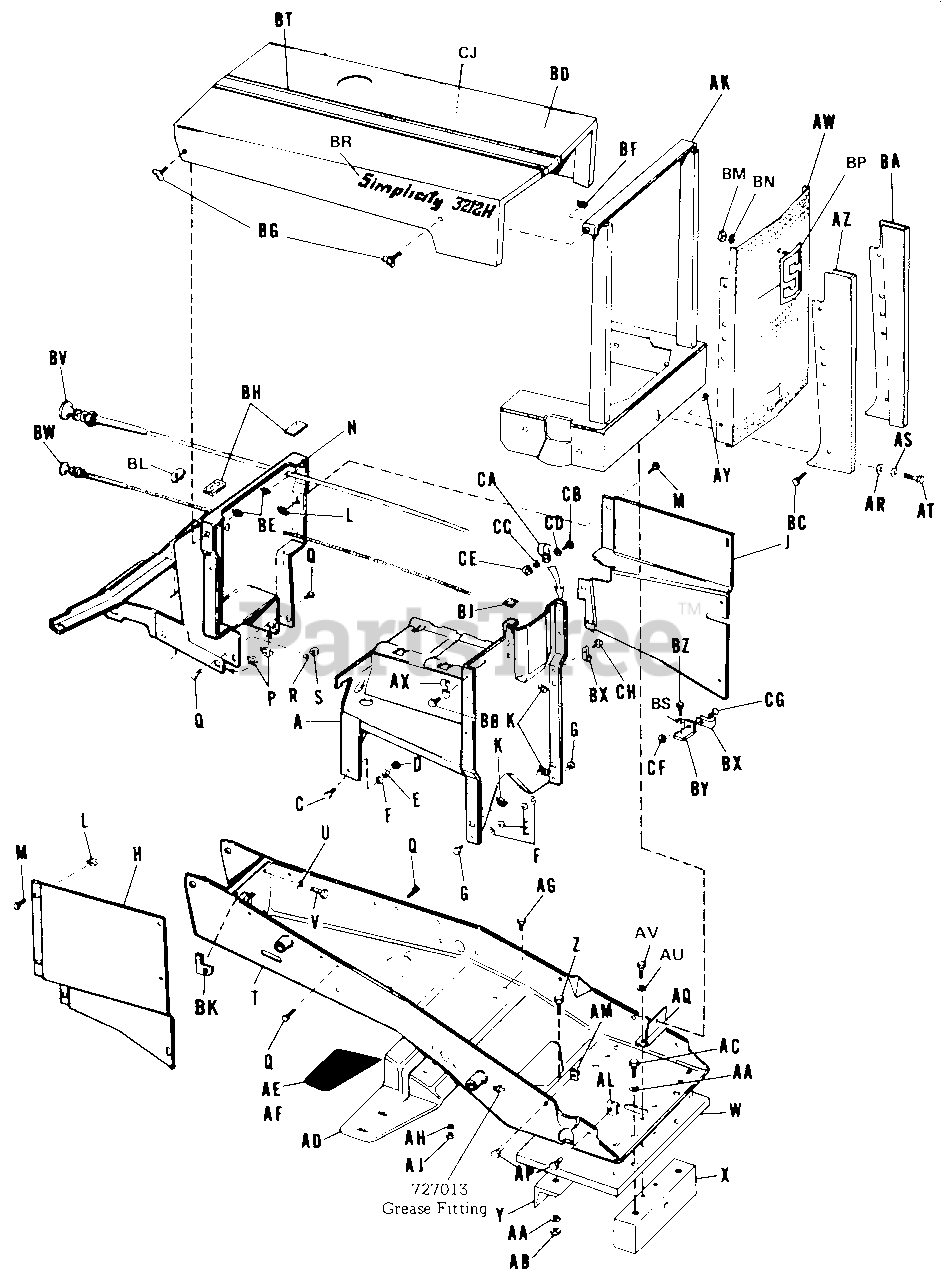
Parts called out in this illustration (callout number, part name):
A	Support Assembly, Fuel Tank & Battery
C	Hex. Cap Screw, 5/16"-18 x 1 1/4"
D	Full Lock Hex. Nut, 5/16"-18
E	Full Hex. Nut, 5/16"-18
F	Lock Washer, 5/16"
G	Hex. Cap Screw, 5/16"-18 x 5/8"
H	R.H. Side Panel
J	L.H. Side Panel
K	Nut Retainer
L	Nut Retainer
M	Hex. Cap Screw, 1/4"-20 x 5/8"
N	Inst. Panel Assembly
P	Nut Retainer (Frame Cover)
Q	Hex. Cap Screw, 1/4"-20 x 1/2"
R	Lock Washer, 1/4"
S	Full Hex. Nut, 1/4"-20
T	Frame Assembly
U	Lock Washer, 7/16"
V	Hex. Cap Screw, 7/16"-14 x 1 1/2"
W	Base Weight
X	Front Support, 1 3/4" x 2 1/2" x 8 5/8"
Y	Angle Assembly (Frame Rear)
Z	Hex. Cap Screw, 7/16"-14 x 1 1/2"
AA	Lock Washer, 7/16"
AB	Full Hex. Nut, 7/16"-14
AC	Hex. Cap Screw, 7/16"-20 x 1 1/2"
AD	Foot Rest
AE	L.H. Foot Rest Pad
AF	R.H. Foot Rest Pad
AG	Hex. Cap Screw, 3/8"-16 x 3/4"
AH	Lock Washer, 3/8"
AJ	Full Hex. Nut, 3/8"-16
AK	Cover & Tube Assembly
AL	Retainer Nut (Front)
AM	Retainer Nut, (Rear)
AP	Hex Screw, Whiz-Lock Flange, 5/16"-18 x 3/4"
AQ	Bracket Assembly
AR	Plain Washer, 5/16"
AS	Lock Washer, 5/16"
AT	Hex. Cap Screw, 5/16"-18 x 1 1/4"
AU	Lock Washer, 5/16"
AV	Hex. Cap Screw, 5/16"-18 x 1 1/2"
AY	Self Tapping Screw, No. 10 x 1/2"
AZ	R.H. Side Plate
BA	L.H. Side Plate
BB	Self-Tapping Screw No. 10-24 x 1 /2"
BC	Self Tapping Screw No. 10 x 1/2"
BE	Nut Retainer (Rear)
BF	Nut Retainer (Front)
BG	Thumb Screw
BK	Rod Guide
BL	Plug Button
BM	Hex Nut 10-24
BN	Lock Washer
BP	Emblem "S"
BQ	Plate, Assy.
BR	Simplicity & Number 3212 Film (R.H.)
BS	Lock Washer, 1/4"
BT	Hood Strip
BU	Hex. Cap Screw, 1/4"-20 x 5/8"
BV	Throttle Control
BW	Choke Control
BX	Bowden Wire Clip
BY	Throttle Cable Bracket
BZ	Self Tapping Screw, 1/4"-20 x 5/8"
CB	Hex. Cap Screw, 1/4"-20 x 5/8"
CC	Lock Washer, 1/4"
CD	Plain Washer, 1/4"
CE	Full Hex. Nut, 1/4"-20
CF	Full Hex. Nut, 10-32
CG	Mach. Rd. Hd. Screw, 10-32 x 3/8"
CH	Self Tapping Rd. Hd. Screw, 10-24 x 1/2"
CJ	Simplicity & Number 3212 Film (L.H.)
